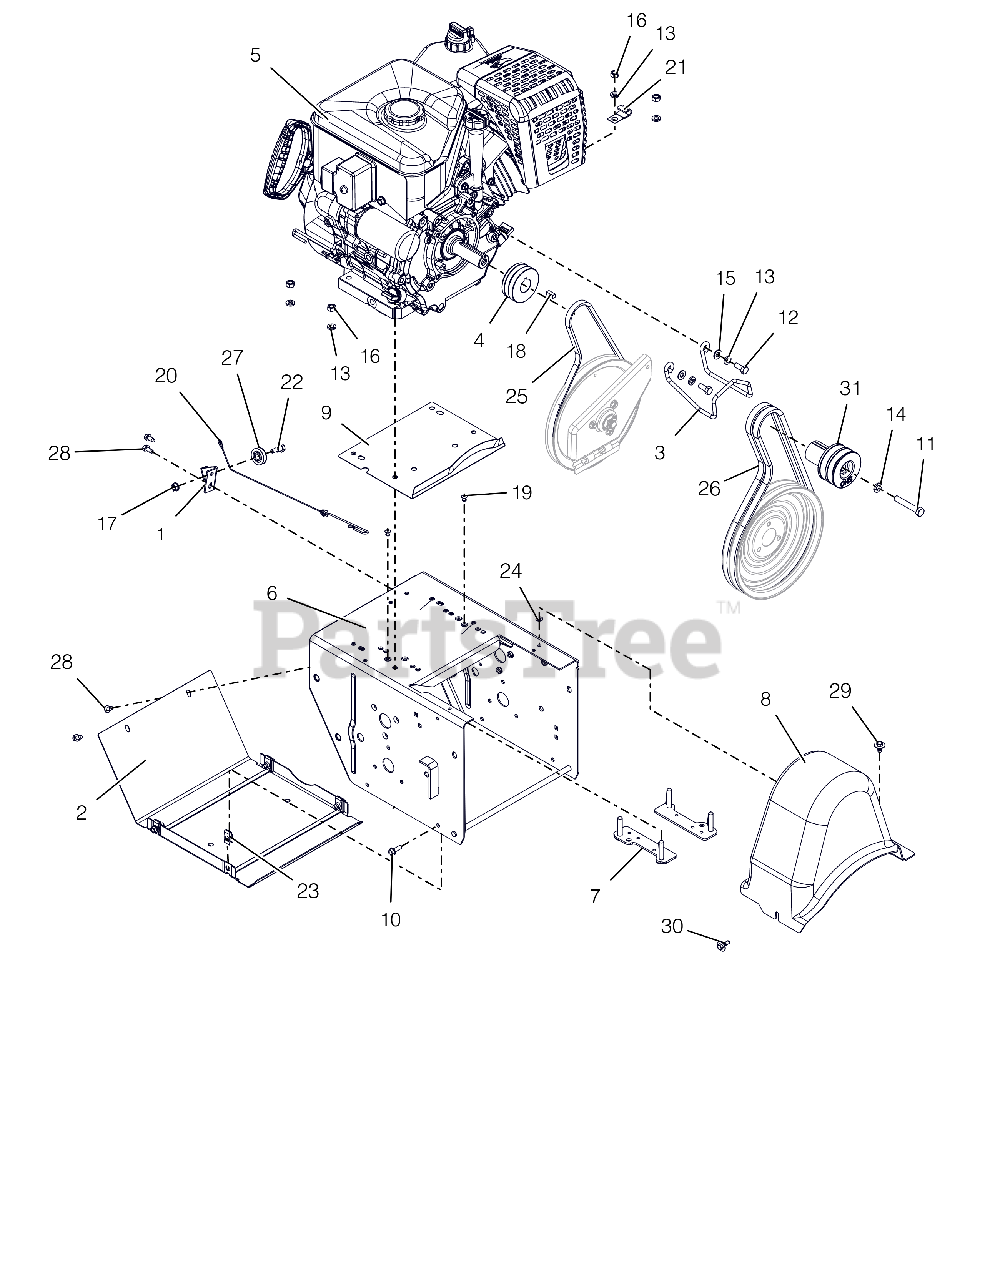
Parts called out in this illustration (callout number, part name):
1	BRACKET, CABLE PULLEY
2	COVER, BOTTOM
3	FINGER, BELT
4	SHEAVE, DRIVE
5	ENGINE, AX369 GEN 3 240V/60W
6	FRAME, MAIN-DELUXE(WELDMENT)
7	STRAP, BOLT-LARGE
8	COVER, BELT-LARGE
9	BAFFLE, WATER - LARGE BLOCK
10	BLT-HEX .25-20X.75 HWH YZ GR5
11	BLT-HEX .38-24X2.25 YWZC GR5
12	BLT-HEX .31-24X.75 YWZC GR5
13	WSHR-LK .312X.097 HVY YWZC
14	@WSHR-LK .38X.094 REG YWZC
15	@WSHR-FL-STL.344X.688X.065YWZC
16	@NUT-HEX .31-18 YWZC
17	@NUT-LK-TOP-FLG .25-20 YWZC
18	KEY-SQ .25X.625X.25 SAE 8630
19	RVT-POP .187 YZ
20	CABLE, LOWER TRACTION,SS & PRO
21	J-CLAMP
22	BOLT, SHLDR-.375X.375X.25-20
23	NUT-RTNR .25-20X.56
24	NUT-PUSH .25X.50 O.D.
25	V-BELT, 3L-WRAPPED
26	V-BELT, HA-RAW EDGE (SET)
27	PULLEY, CABLE
28	SCR-TAP .25-20X.50 HWH TR YWZ
29	SCR-TAP .25-20X.50 LGHWH TR YZ
30	SCR-TAP .25-20X.5 CAPTIVE
31	SHEAVE,ATTACHMENT-SHO 2 GRV
